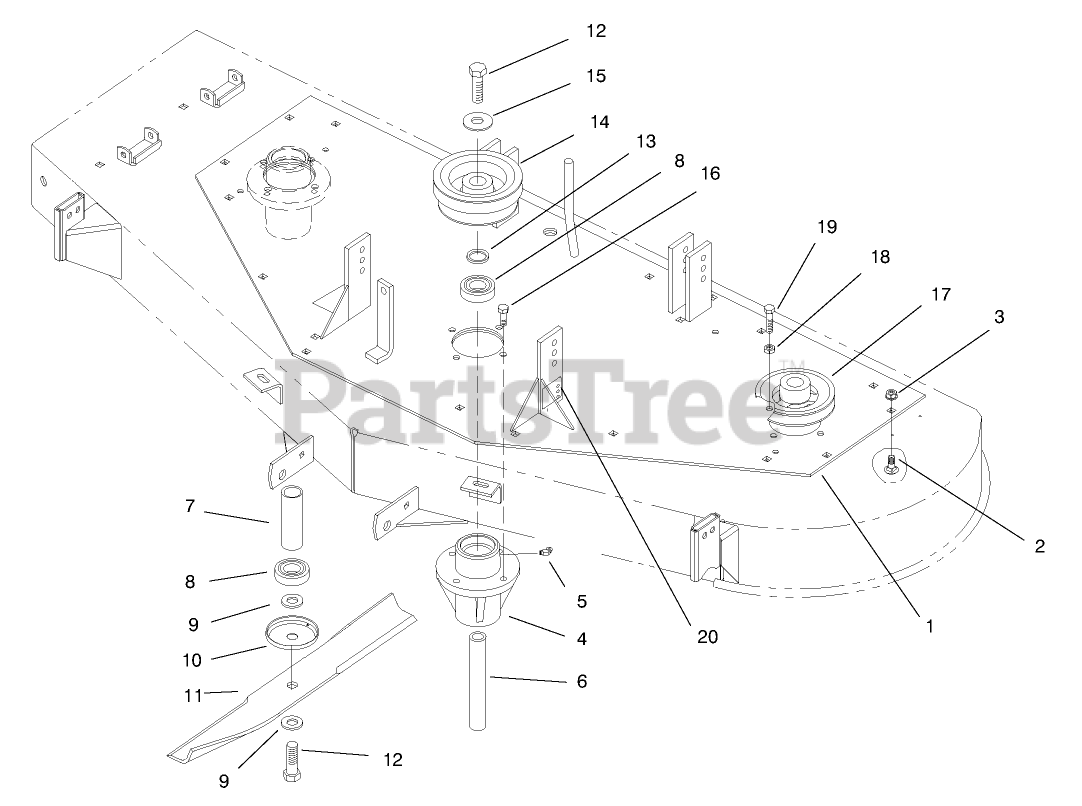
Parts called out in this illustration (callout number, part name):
1	ASS'Y PLATE
2	BOLT-CARR
3	NUT-LOCK, NI
4	HOUSING-SPINDLE
5	FITTING-GREASE
6	SHAFT-SPINDLE
7	TUBE
8	BEARING-BALL
9	WASHER-SPECIAL
10	CUP-SPINDLE
11	BLADE
12	SCREW-HH
13	SPACER
14	PULLEY-CENTER
15	WASHER-SPECIAL
16	SCREW-HH, LOCK
17	PULLEY-OUTER SPIND
18	NUT-JAM
19	SCREW-HH
20	DECAL - HOC
